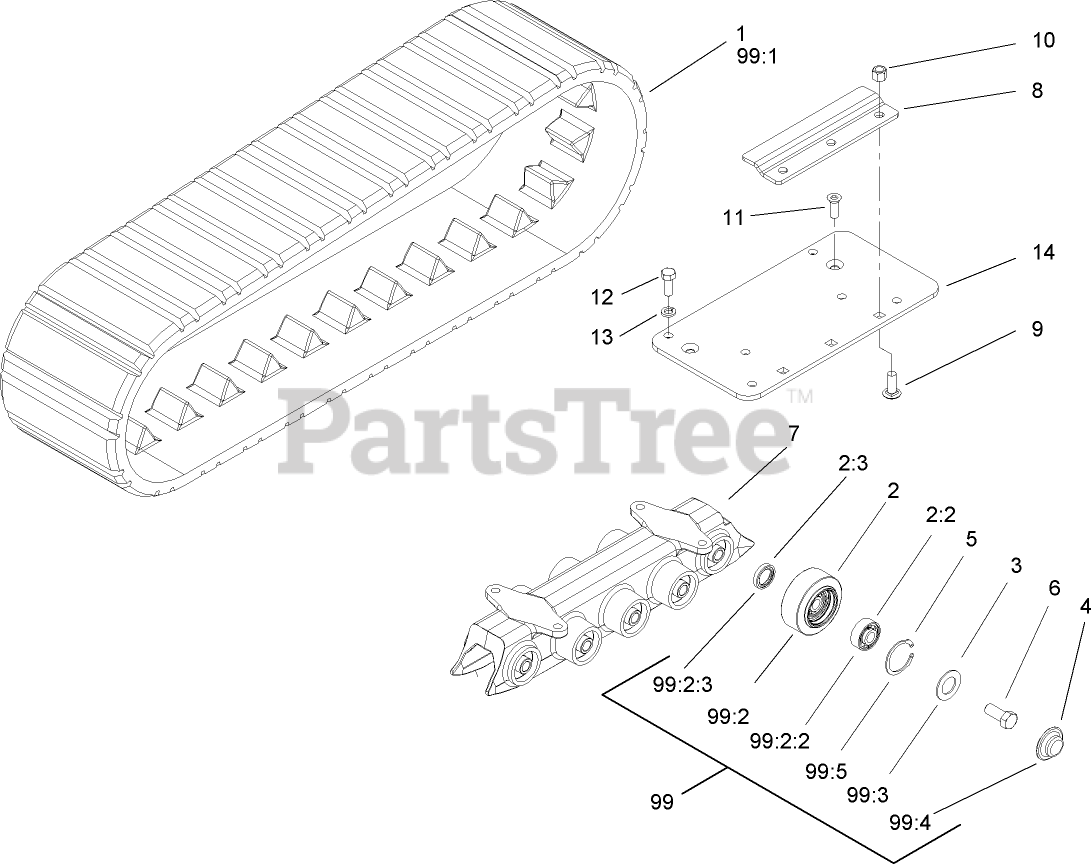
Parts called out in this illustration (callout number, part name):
1	TRACK
2	Road Wheel ASM
2:2	BEARING
2:3	SEAL-OIL
3	Gasket-Bogie
4	CAP-WHEEL, BEARING
5	RING-SNAP, INTERNAL
6	SCREW-HH
7	GUIDE-TRACK,REFIT
8	PLATE-CLAMP
9	SCREW-CARR, SHORT NECK
10	NUT-LOCK, NI
11	SCREW-HSFH
12	SCREW-HH
13	WASHER-LOCK
14	LH GUIDE ADAPTER PLATE ASM
99	TRACK REBUILD KIT
99:1	TRACK
99:2	Road Wheel ASM
99:2:2	BEARING
99:2:3	SEAL-OIL
99:3	Gasket-Bogie
99:4	CAP-WHEEL, BEARING
99:5	RING-SNAP, INTERNAL
